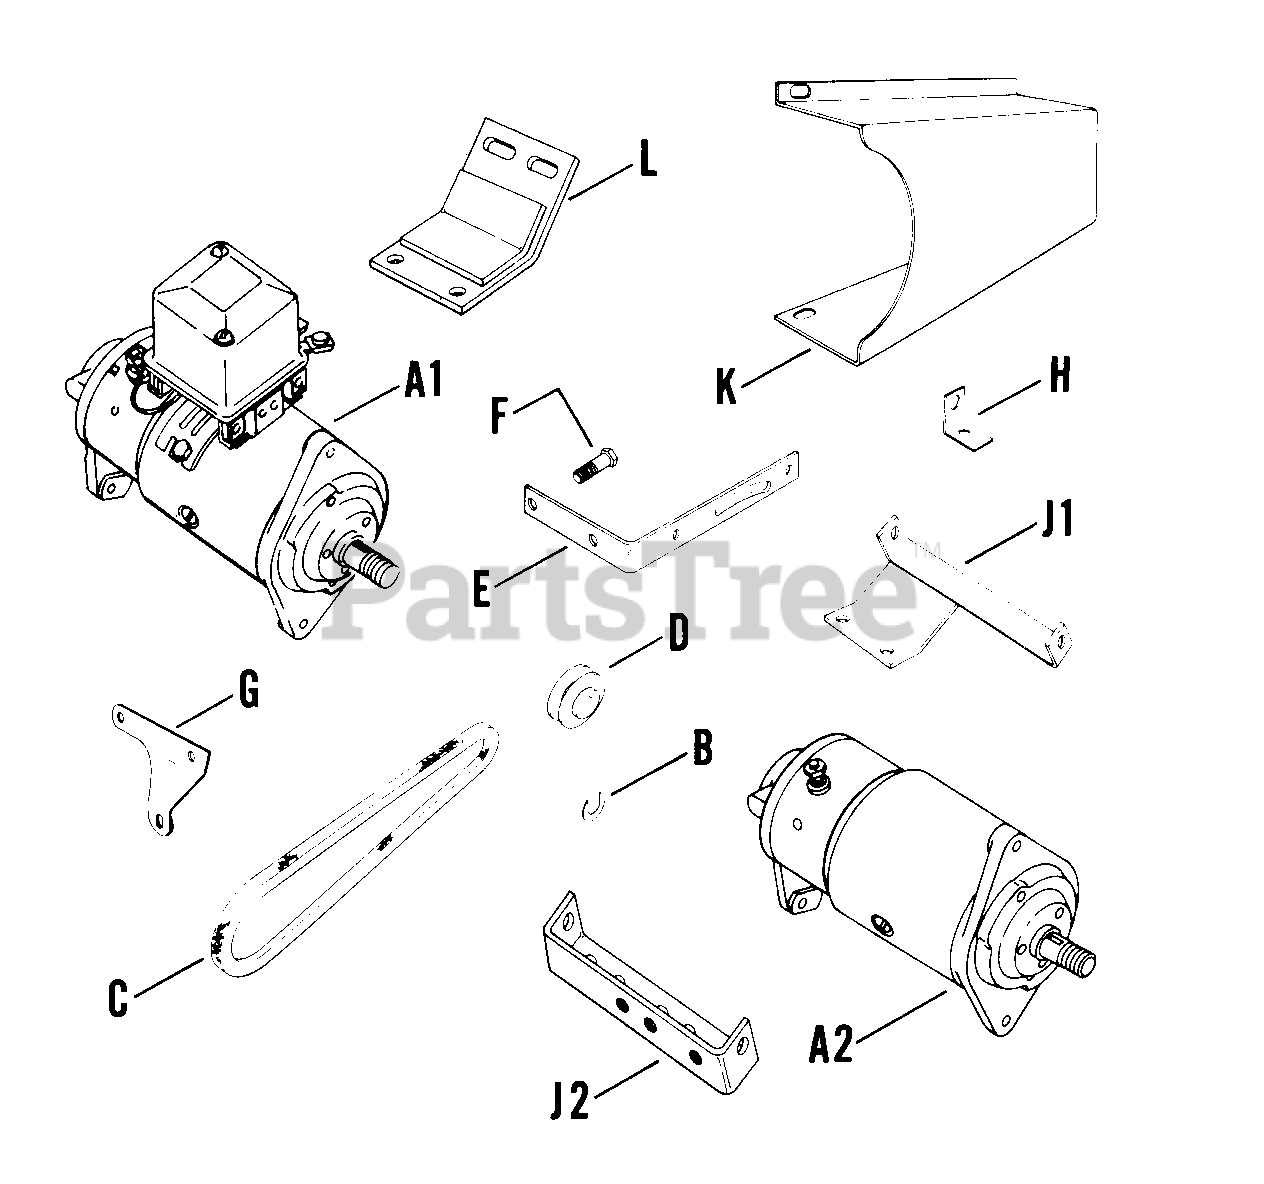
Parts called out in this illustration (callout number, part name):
A1	STARTER - DISCONTINUED
B	SHIM - DISCONTINUED
C	BELT - DISCONTINUED
D	PULLEY - DISCONTINUED
E	SUPPORT - DISCONTINUED
F	SCREW - DISCONTINUED
J2	BRACKET - DISCONTINUED
